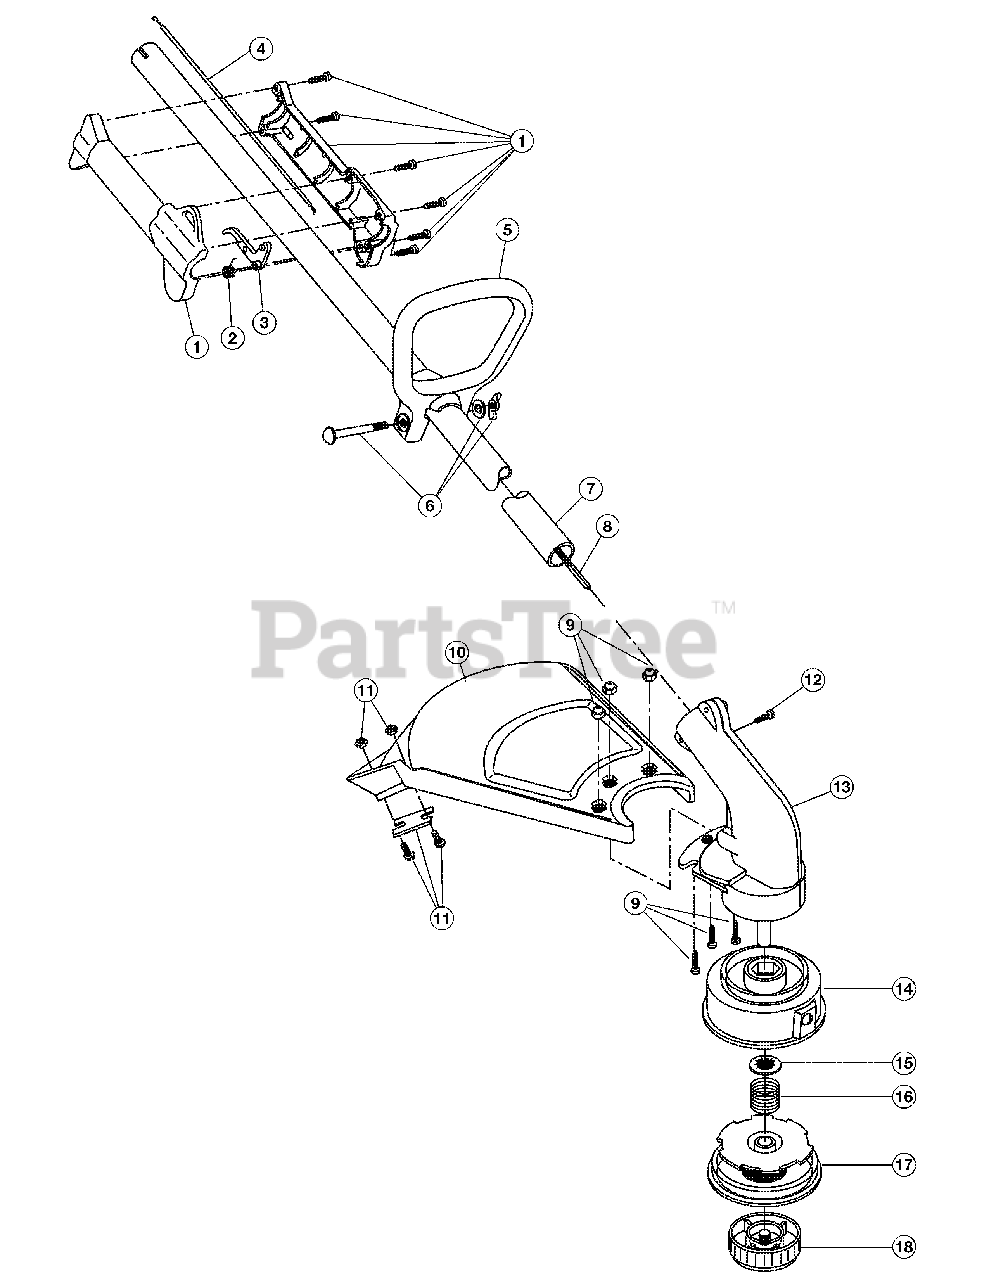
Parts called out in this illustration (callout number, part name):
1	Throttle Housing Assembly
2	Throttle Trigger Spring
3	Throttle Trigger
4	Throttle Cable
5	D-Handle
6	D-Handle Hardware Assembly
7	Drive Shaft Housing Assembly
8	Flexible Drive Shaft Assembly
9	Guard Mounting Screw Assembly
10	Guard Assembly
11	Blade Assembly
12	Anti-Rotation Screw
13	Gearbox Assembly
14	Out Spool Assembly
15	Retainer
17	Inner Reel
18	Bump Head Knob Assembly
